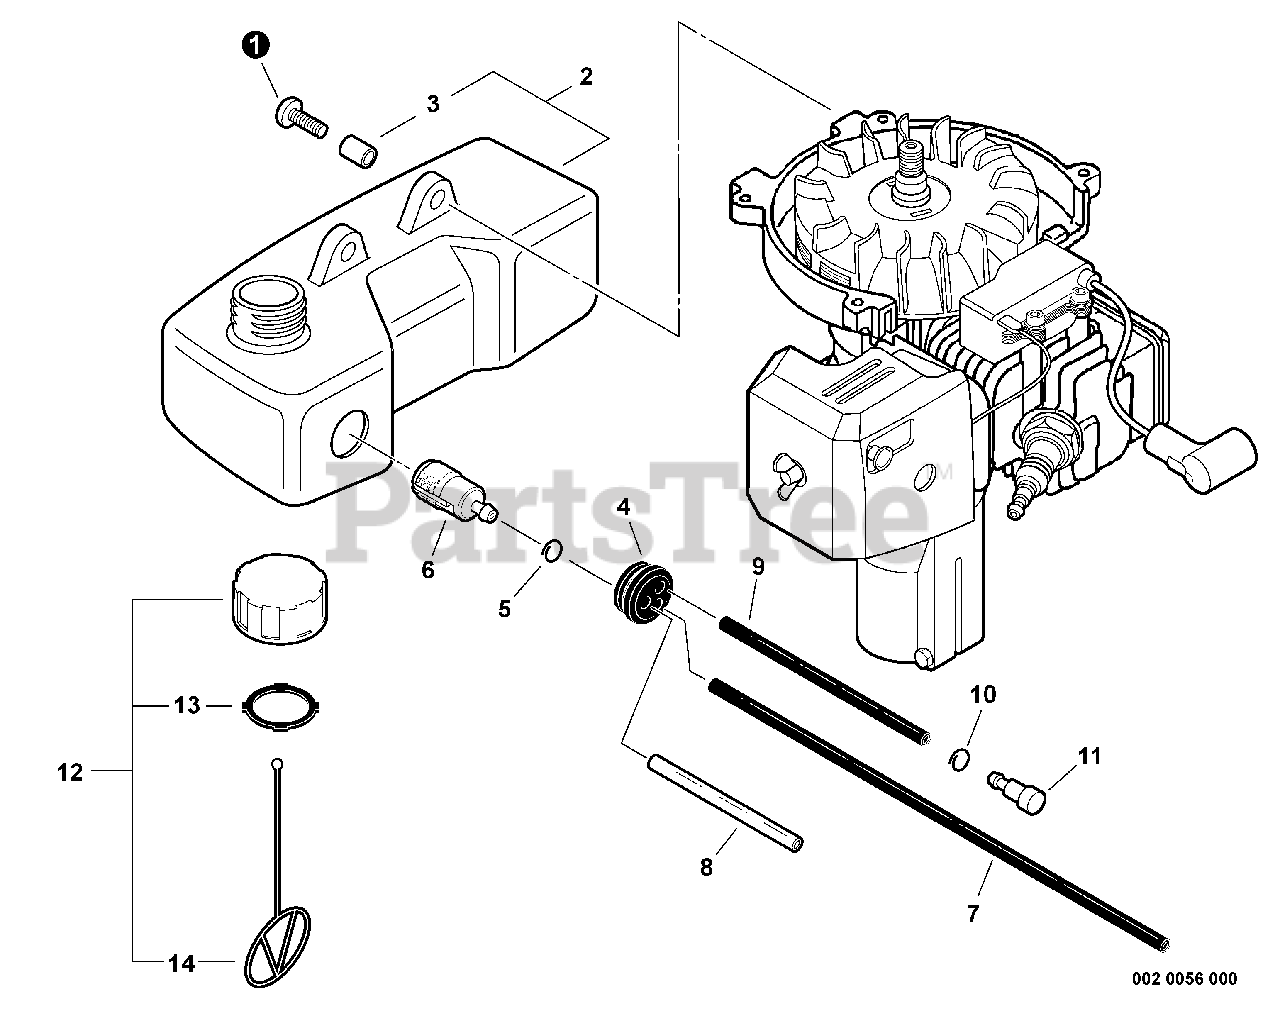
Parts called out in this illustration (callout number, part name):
1	SCREW 5×15
2	TANK, FUEL
3	SPACER 6.2×7.8×6
4	GROMMET, FUEL Ø5
5	CLIP 6 MM
6	FILTER, FUEL
7	PIPE, FUEL 3×5×210 BLACK
8	PIPE, FUEL 3×6×50
9	PIPE, FUEL 3x-5x-70 BLACK
11	VENT ASSY
12	CAP ASSY
13	GASKET, FUEL CAP
14	CONNECTOR, CAP L= 100 MM
